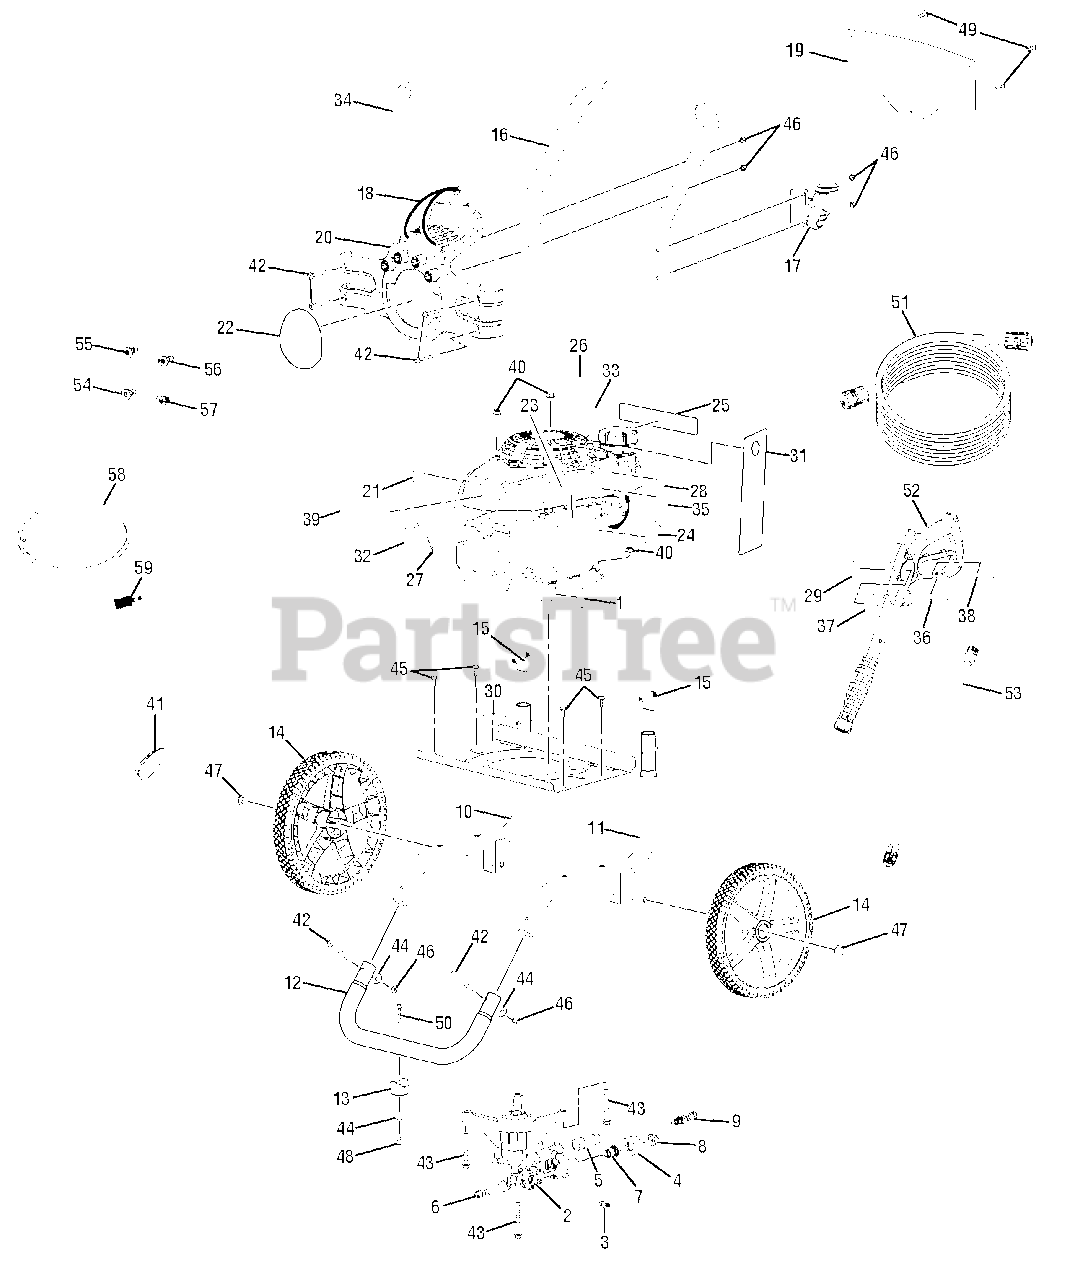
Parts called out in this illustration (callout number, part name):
1	Output Shaft Key
2	Pump
3	Detergent Injector Assembly
5	Outlet Tube
6	Thermal Release Valve
8	Filter Screen
9	Unloader Assembly
10	Main Frame Assembly
11	Main Frame Assembly
12	Front Frame Assembly
14	Wheel
15	Spring Clip
16	Handle Assembly
17	Trigger Handle Holder
18	Bungee Cord Assembly
19	Quick Start Panel
20	Hose and Nozzle Holder
21	Hot Surface Label
22	Performance Label
23	Inquiries Label
24	Choke Label
25	Danger Label (Eng/Sp)
26	Combustion Label
28	Do Not Mix Label
29	Logo Label
30	Oil Fill Location Label
31	Danger Hangtag
32	Dipstick Hangtag
33	No E85 Label
34	Nozzle Hangtag
35	Engine On/Off Label
36	Warning Label (Fr/Sp)
37	Warning Label
38	Wand Rating Label
39	Honda Brand Label
40	Lock Nut (M8 x 1.25)
42	Screw (M6 x 48 mm, T30 Torx Hd.)
43	Bolt (M8 x 60 mm, Hex Flange Hd.)
44	Washer (1/4 in.)
45	Bolt (M6 x 16 mm, Hex Flange Hd.)
46	Lock Nut (M6)
47	Push Cap Nut (1/2 in.)
48	Lock Nut (1/4-20)
49	Screw (#6-20 x 3/8 in.)
50	Screw (1/4-20 x 1.85 in., T30 Torx Pan Hd.)
51	High Pressure Hose
52	Trigger Handle Assembly
53	Spray Wand Assembly
54	0deg Nozzle
55	25deg Nozzle
56	40deg Nozzle
57	Soap Nozzle (Blue)
58	Chemical Siphon Tube
59	Chemical Siphon Filter
